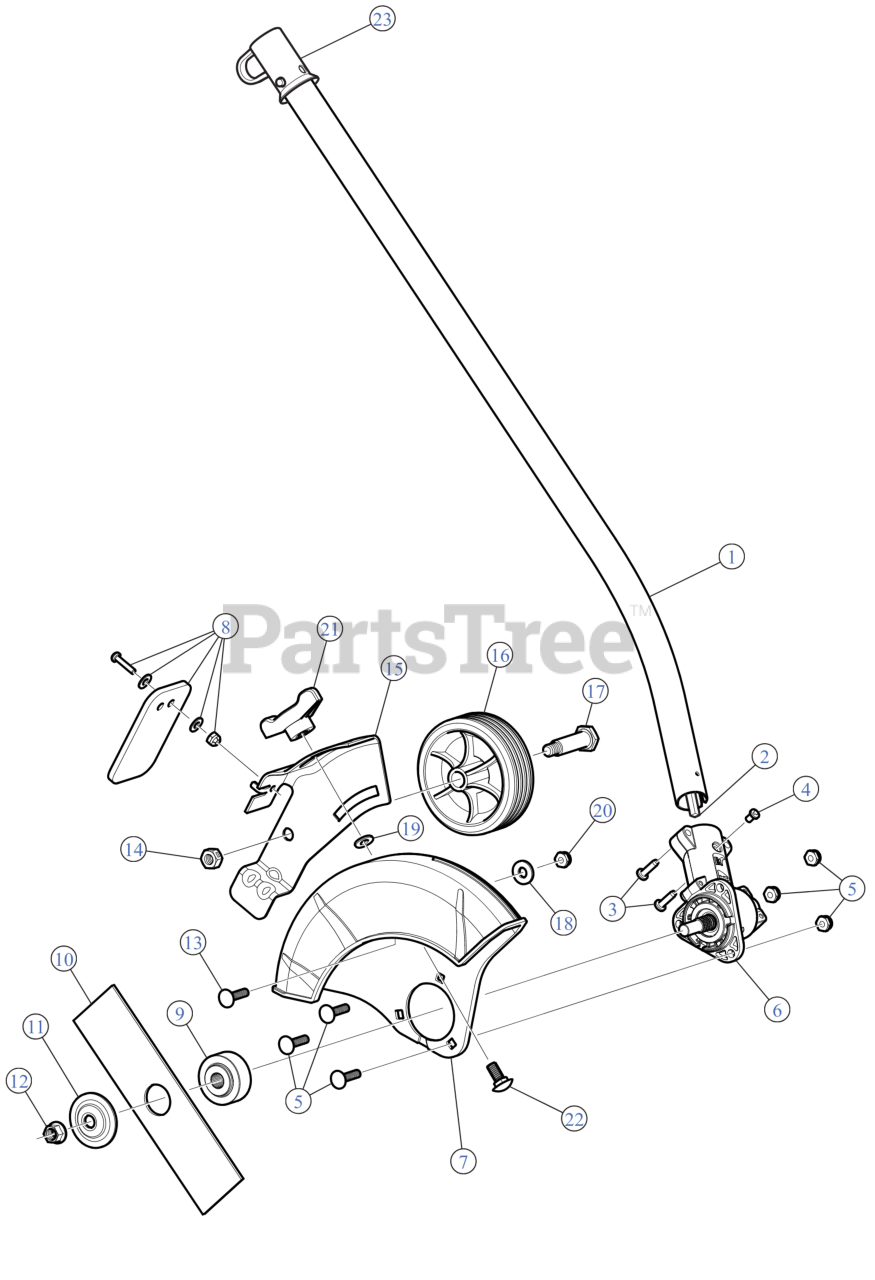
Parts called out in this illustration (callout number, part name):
1	BOOM ASSEMBLY LE
2	LOWER DRIVE SHAFT
3	SCREW #10-24X11/16 T-25
4	SCREW, 8-32 x .312 P
5	HDWR ASM:GUARD MT
6	GRBX ASSEMBLY
8	DEFLECTOR W/HDW
9	SPACER
10	8" EDGER BLADE
11	WASHER-BLADE CLAMP BRUSH CUT
12	BLADE LOCK NUT
13	BOLT:WHEEL MT BRACKET
14	LOCK NUT 3/8-16
15	BRACKET GUARD
16	WHEEL 3.75" (WHITE)
17	SHOULDER SCREW 0.498x1.494 3/8-16
18	FLAT WASHER
19	WASHER .406X1.0X.095
20	NUT 1/4-20 NYLOC
21	WING KNOB 5/16-18
22	CARRIAGE BOLT 5/16-18 x .75
23	HANGER
